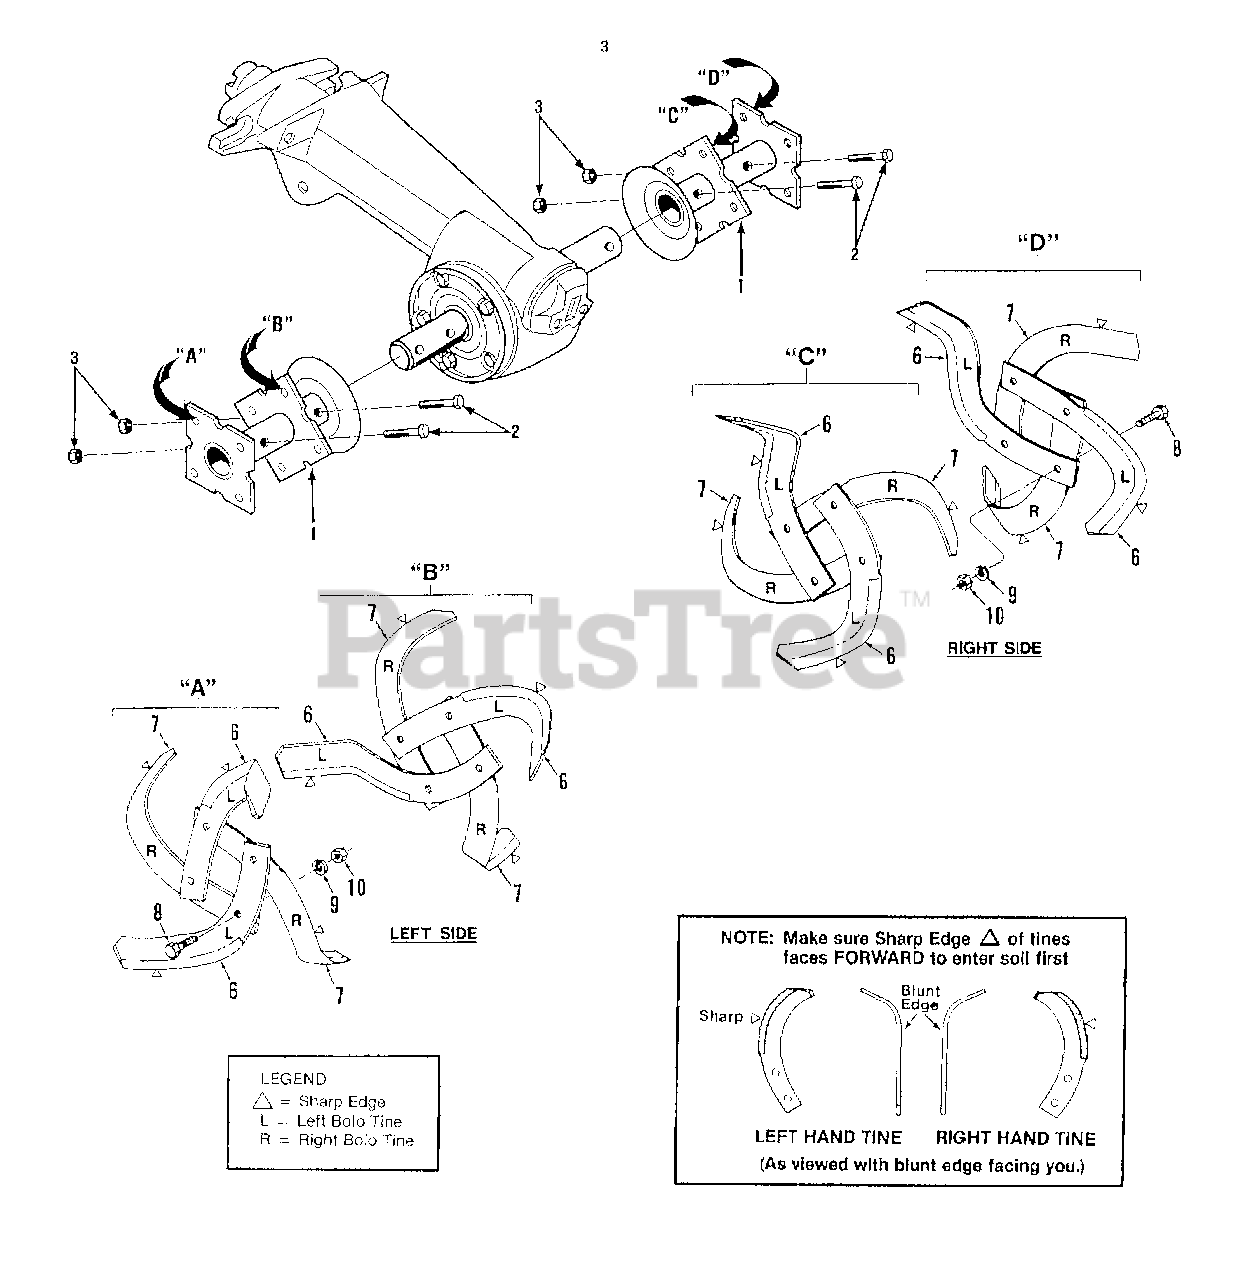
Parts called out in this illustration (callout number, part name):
1	HOLDER-TINE HORSE (RED)
2	SCR-HH 3/8-16X2.00 G8
3	NUT-H/LK 3/8-16
4	THIS REF. NO. NOT USED
5	THIS REF. NO. NOT USED
6	TINE-BOLO LT W/HDW(INCL. TWO EACH OF REF. NO.'S 8,9 AND 10)
7	TINE-BOLO RT W/HDW(INCL. SAME HARDWARE AS REF. NO.6)
8	SCR-HH 3/8-16X1.0 G5 ZP
9	WASHER-LK .375 @ DEPL
10	NUT-HEX 3/8-16 ZP
